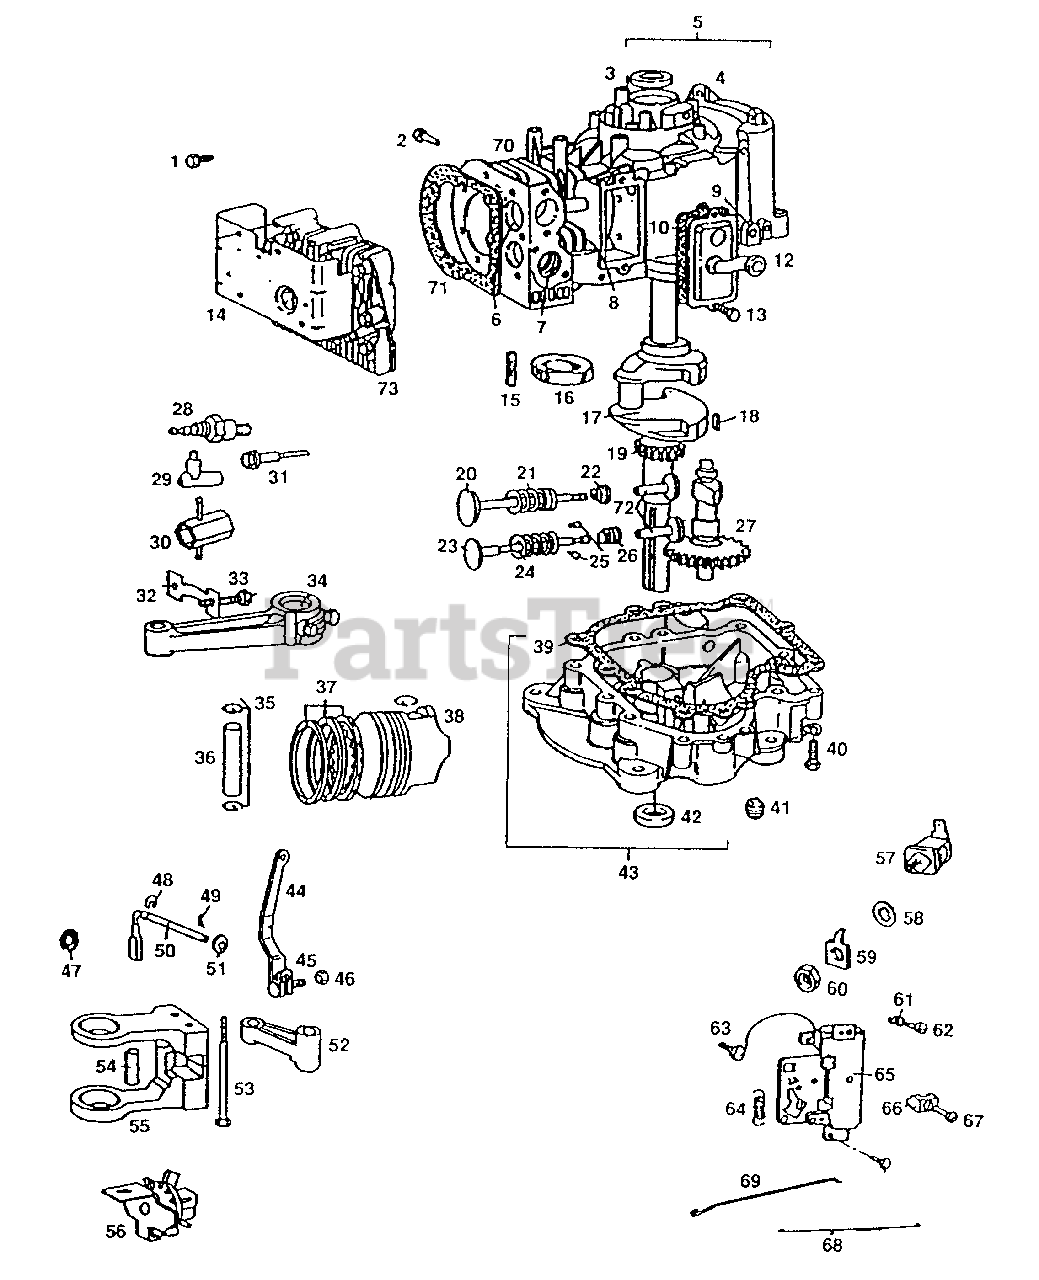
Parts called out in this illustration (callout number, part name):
1	Screw, Blower Housing Mounting Sem
2	Screw, Cylinder Shield Mtg. Sem
3	Bearing, Cylinder
4	Seal, Oil
5	Cylinder Assembly
6	Seat, Intake Valve
7	Seat, Exhaust Valve
8	Guide, Exhaust Valve
9	Bushing, Governor Crank (1/4" ID)
10	Gasket, Valve Cover
11	Breather Assembly
12	Tube, Breather
13	Screw, Sem
14	Cover, Cylinder Head
15	Pin, Eccentric
16	Eccentric
17	Crankshaft
18	Key, Flywheel
19	Gear, Timing
20	Valve, Intake
21	Spring, Intake Valve
22	Retainer, Intake Valve
23	Valve, Exhaust
24	Spring, Exhaust Valve
25	Retainer, Exhaust Valve Rotocoil (2)
26	Rotocoil, Exhaust Valve
27	Gear, Cam
28	Plug, Spark (1 1/2" high - 37-42mm)
29	Elbow, Spark Plug
30	Wrench, Spark Plug
31	Screw, Cylinder Head (3" long)
32	Lock, Connecting Rod Screw
33	Screw, Connecting Rod
34	Rod Assembly, Connecting
35	Lock, Piston Pin
36	Pin Assembly, Piston -
36	Pin Assembly, Piston - .005 0.S.
37	Ring Set, Piston -
37	Ring Set, Piston - .010" O.S.
37	Ring Set, Piston - .020" O.S.
37	Ring Set, Piston - .030" O.S.
38	Piston Assembly Standard
38	Piston Assembly - .010" O.S.
38	Piston Assembly - .020" O.S.
38	Piston Assembly - .030" O.S.
38	Piston Ring Sets For Chrome Ring Set -
39	Gasket, Crankcase Cover (1/64" thick)
40	Screw, Base Mounting Sem
41	Plug, Oil Drain
42	Seal, Oil
43	Base, Engine
44	Lever Assembly, Governor (For 1/4" dia Crank)
45	Bolt, Governor Lever
46	Nut, Hex 10 - 24
47	Seal, Oil
48	Retainer, E-Ring
49	Cotter, Hairpin
50	Crank, Governor (1/4" dia.)
51	Washer, Governor Crank (1/4" I.D.)
52	Link, Counterweight
53	Screw, Counterweight (1)
54	Pin, Counterweight (1)
55	Counterweight Assembly
56	Oil Slinger, Governor
57	Insulator Assembly
58	Washer, Lock, Shake-proof
59	Terminal, Spade
60	Nut, Hex 8 - 32
61	Spring, Throttle Adjustment
62	Screw, Machine Fill Hd. 8 - 32 x 1/2"
63	Screw, Carburetor
64	Spring, Governor
65	Plate, Governor Control (Choke-A-Matic)
66	Clamp, Casing
67	Screw, Sem
68	Spring, Governor Link
69	Link, Governor
70	Shield, Cylinder
71	Gasket, Cylinder Head
72	Tappet Valve
73	Head, Cylinder
